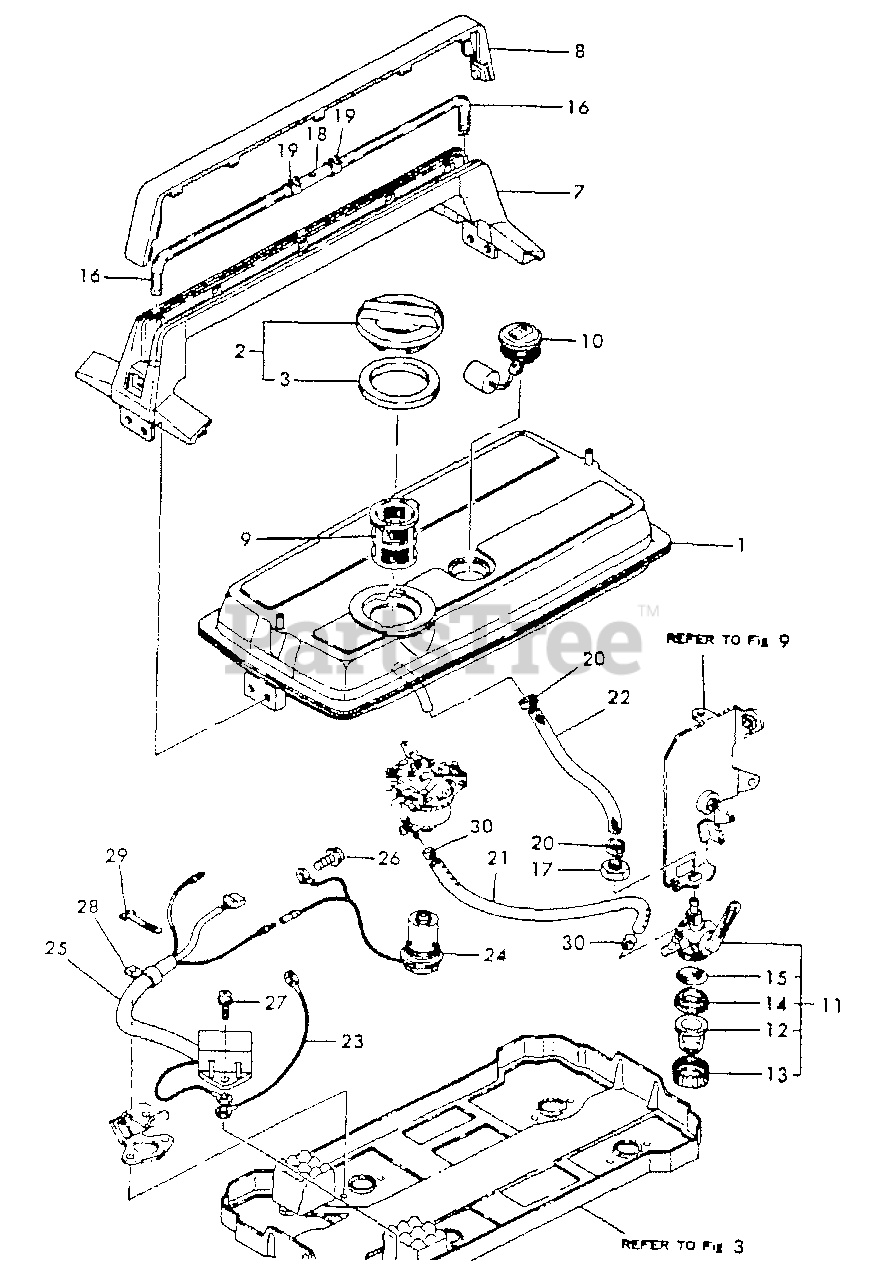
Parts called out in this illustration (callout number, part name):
1	FUEL TANK ASSY
2	CAP ASSY
3	GASKET, CAP
7	FUEL CAP ASSY
8	CAP, GRIP
9	FILTER, FUEL
10	GAUGE, FUEL
11	FUEL COCK ASSY
12	BOWL, STRAINER
13	RETAINER
14	GASKET
15	FILTER, FUEL
16	HOSE
17	LOCKNUT - 12 -- PLATED
18	JOINT
19	CLAMP, HOSE - 10
20	CLAMP, HOSE
21	PIPE - FUEL
22	PIPE - FUEL
23	WIRE A
24	SENSOR, OIL LEVEL
25	UNIT, OIL SENSOR
26	SCREW - 6X12
27	SCREW - 6X12
28	CLAMP
29	CLAMP
30	CLAMP, HOSE - 10
